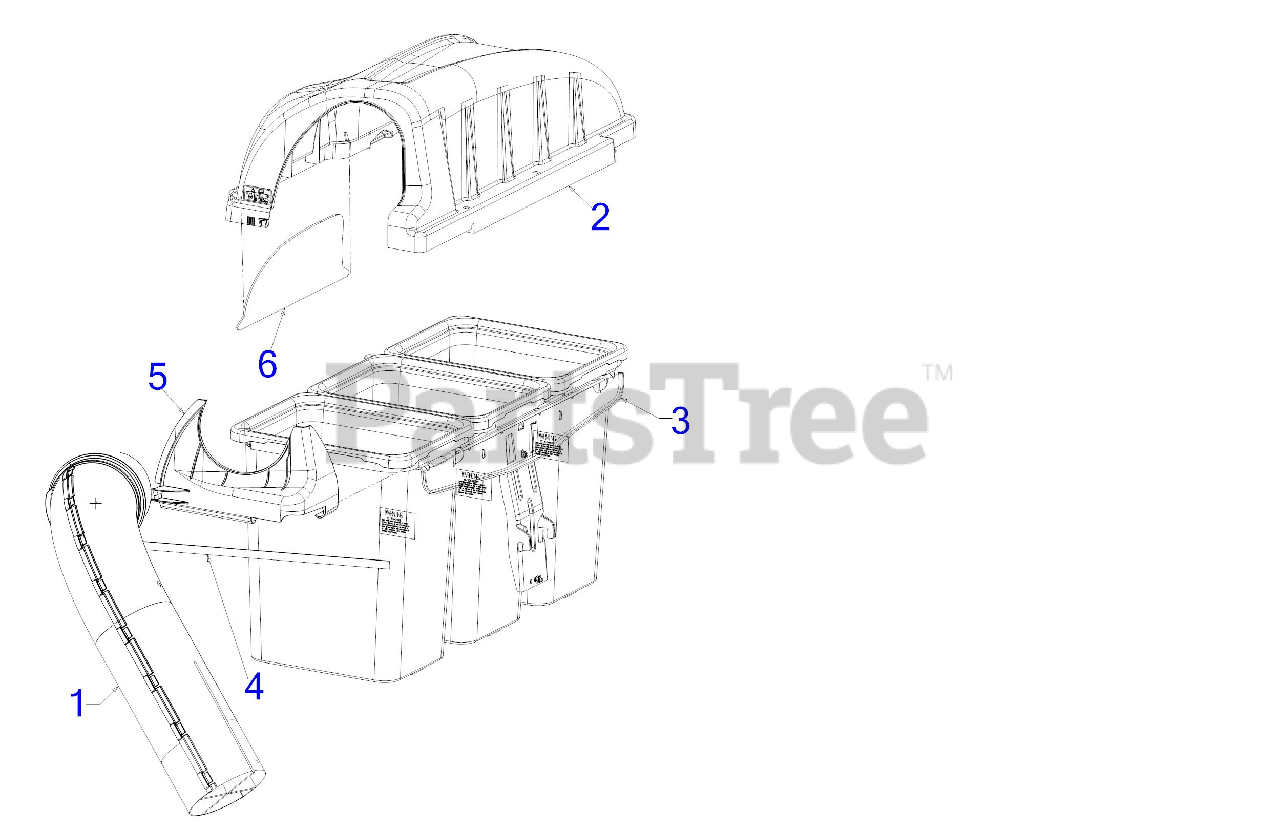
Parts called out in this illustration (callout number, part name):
1	UPPER CHUTE ASSEMBLY
2	TRIPLE BAGGER COVER
3	COMPLETE BAG ASSEMBLY
4	FOAM TAPE .75 WIDE x .125 THICK
5	UPPER CHUTE SUPPORT
6	BAGGER COVER SCREEN
